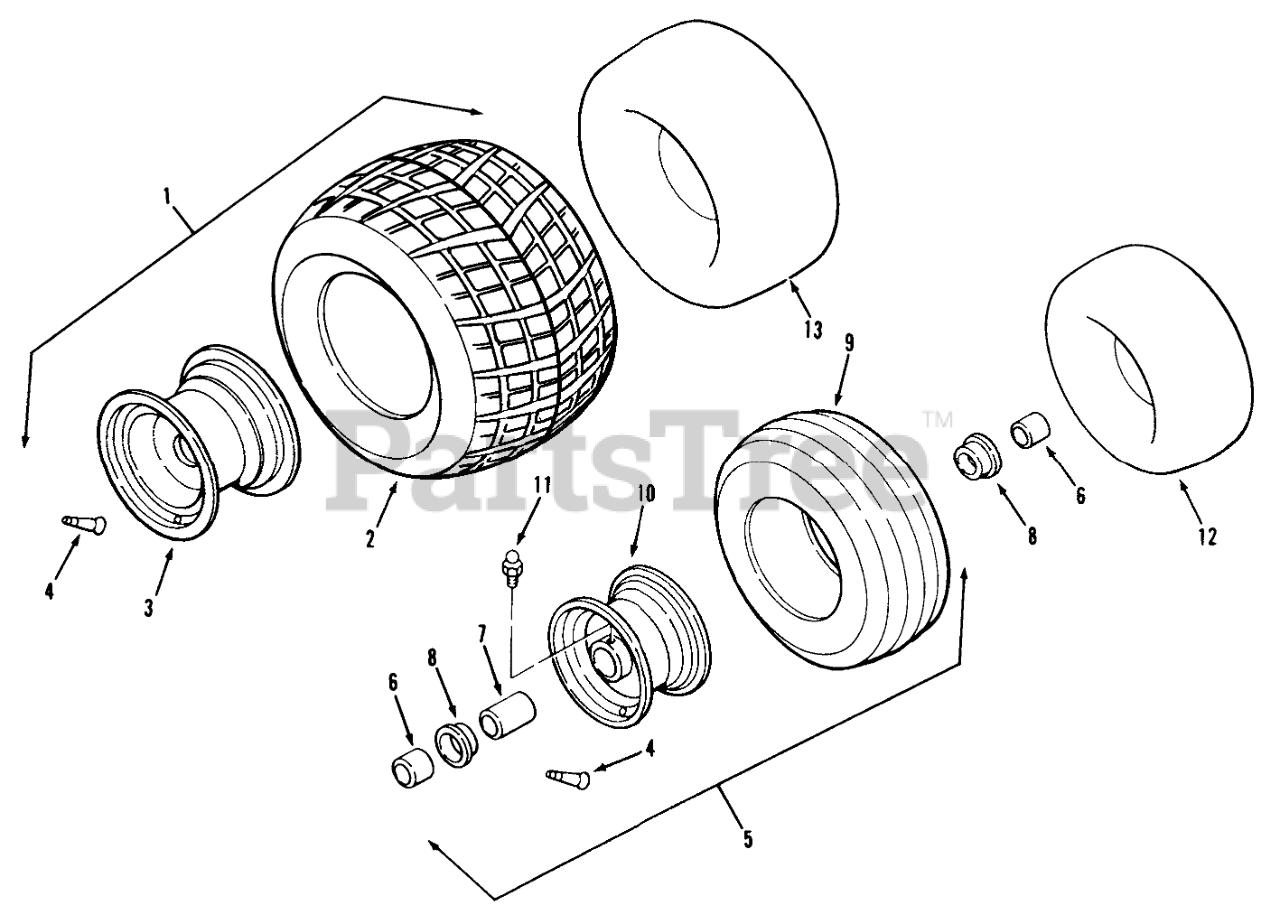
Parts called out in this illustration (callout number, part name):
2	TIRE 22 X 11.00-8
3	Wheel-Rear, Silver
4	VALVE
6	SPACER
7	SPACER FRT WHEEL INN
8	BEARING BALL
9	TIRE-FRT 13X5.00-6
10	WHEEL FT SLUV 10239K
11	Zerk
12	INNER TUBE
13	Tube-Rear
